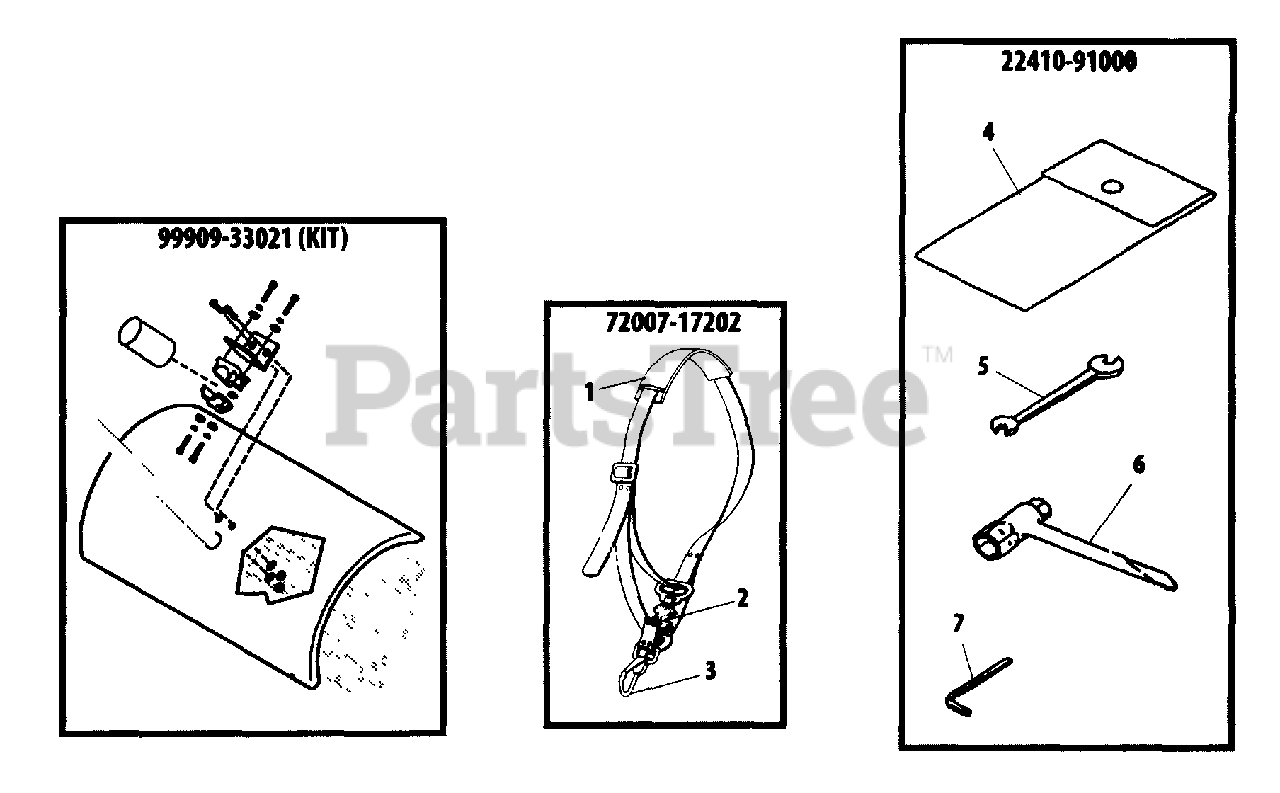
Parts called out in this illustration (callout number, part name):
1	PAD, SHOULDER
3	HOOK, SNAP
4	BAG, TOOL
5	SPANNER 8×10
6	T-WRENCH 13×19 MM
7	WRENCH, ALLEN 4 MM
